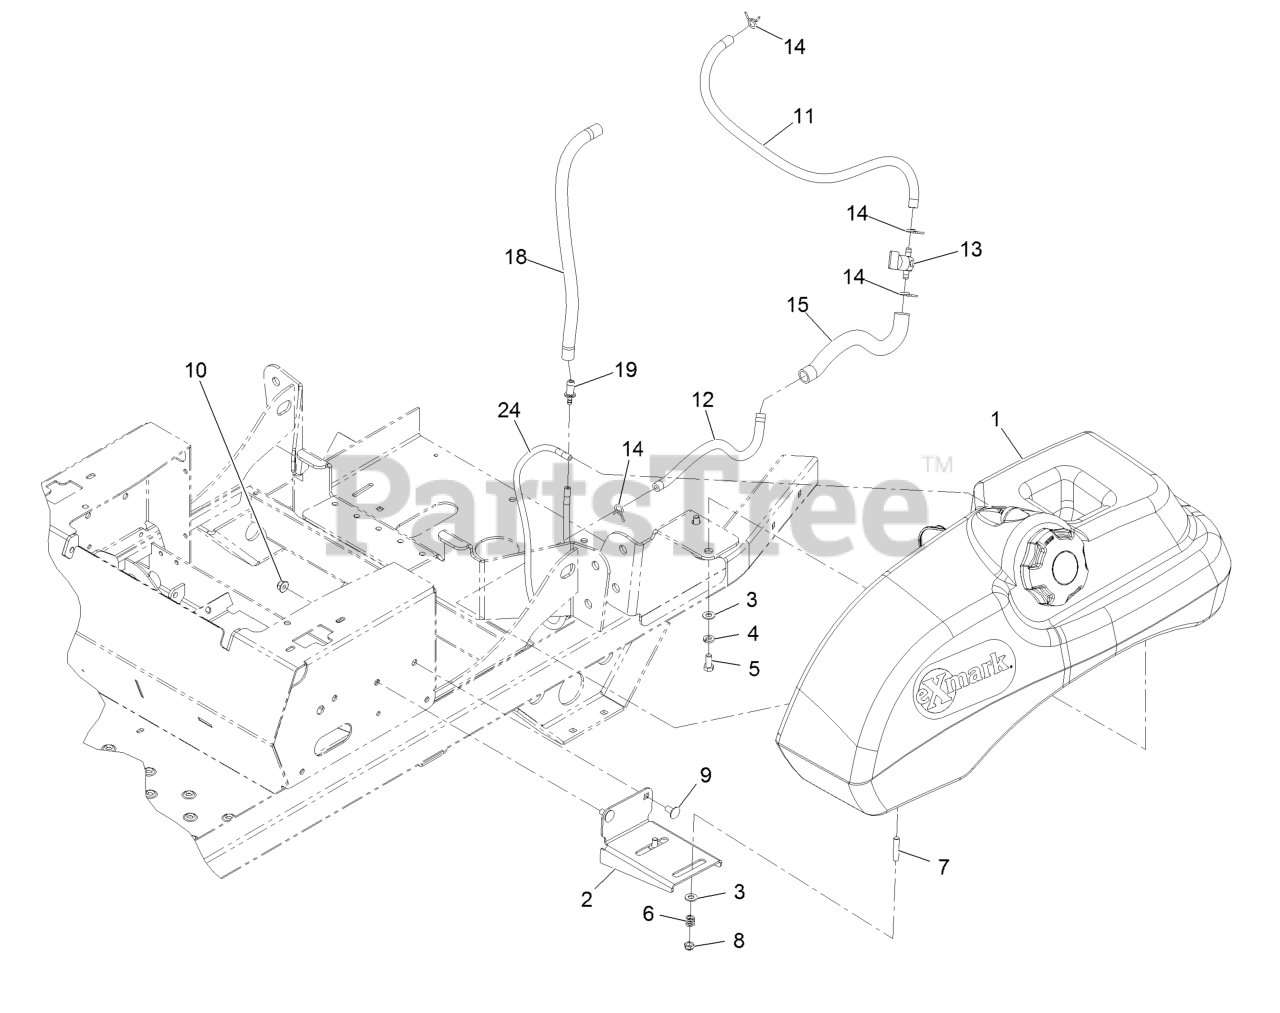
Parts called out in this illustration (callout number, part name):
1	ASM-FUEL TANK
2	BRACKET-TANK AND FENDER
3	WASHER-PLAIN
4	WASHER-LOCK
5	SCREW-HH
6	SPRING-TANK, FUEL
7	STUD
8	NUT-LOCK, NI
9	SCREW-CARR
10	NUT-HF, NI
11	HOSE-FUEL
12	HOSE-FUEL
13	VALVE-FUEL
15	CONDUIT-FUEL LINE
18	HOSE-FUEL
19	FITTING-ORIFICE, STRAIGHT
24	HOSE,EMISSIONS
